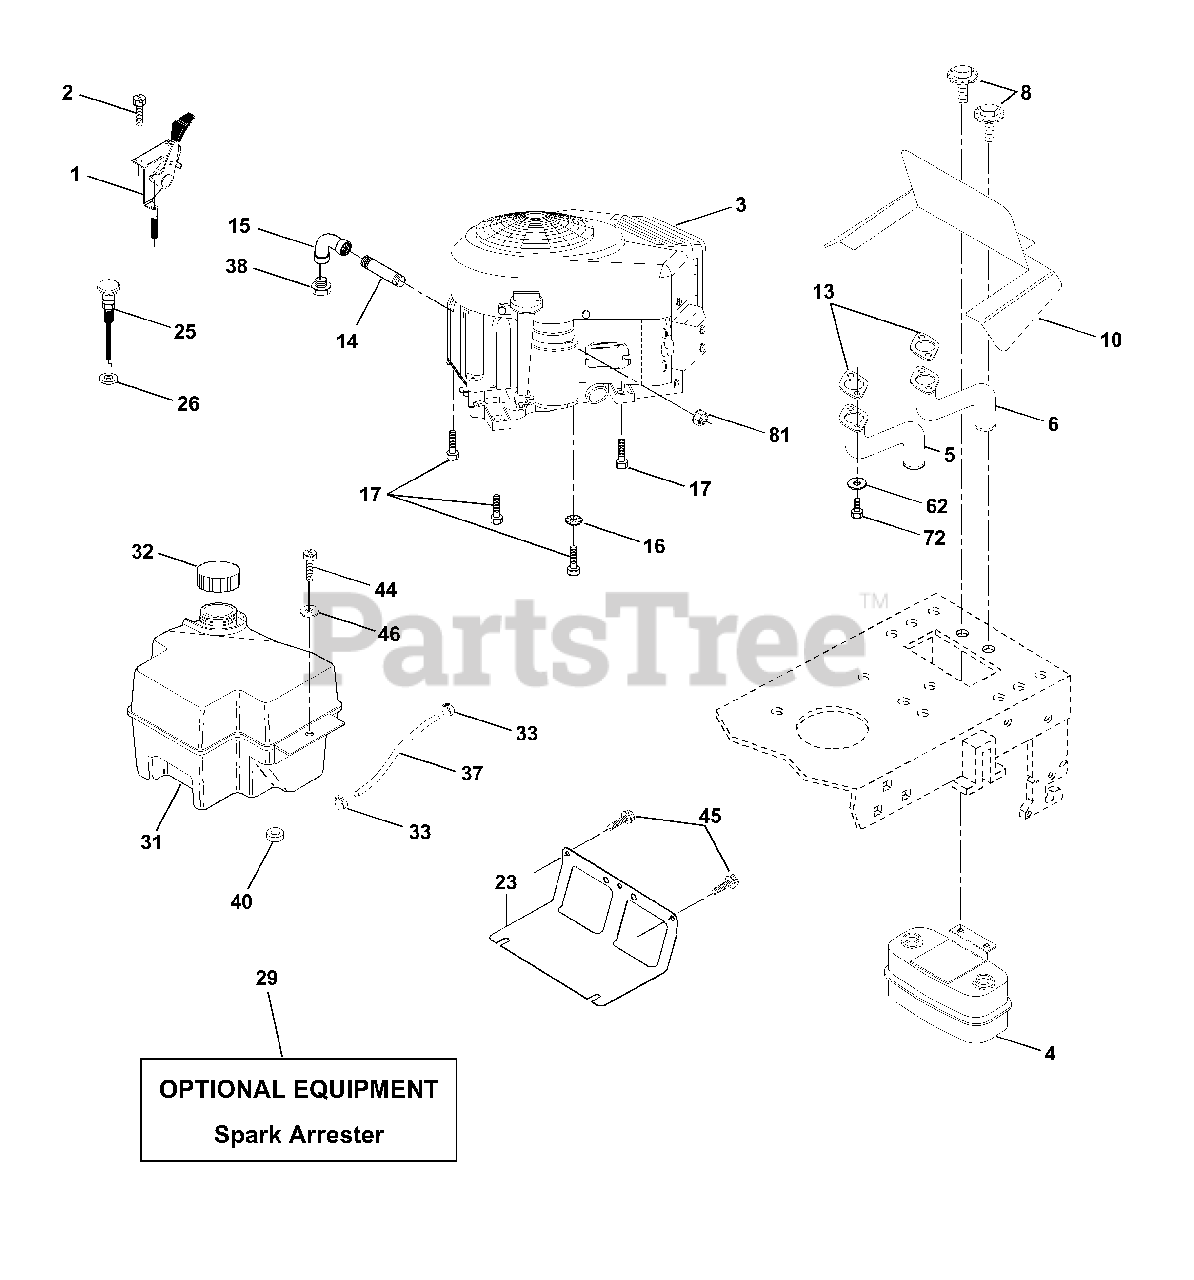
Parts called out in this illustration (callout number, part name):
1	Control, Throttle
4	Muffler, Asm. Twin Lo-Tone
5	Pipe Exhaust Intek 20 RH
6	Pipe Exhaust Intek 20 LH
8	Bolt 5/16-18 UNC x 3/4
10	Shield Browing B&S Intek II
13	Muffler Gasket
14	Nipple, Pipe
15	Elbow, Standard 90°, 3/8-18 NPT
16	Washer, Lock Ext tooth 3/8
17	Screw Thdrol 3/8-16 x 1-1/2
23	Shield, Browning/Debris Guard
25	Control Choke
26	Nut Keps 3/8-24 UNF
29	Arrester, Spark
31	Tank, Fuel
32	Cap Gauge, Fuel
33	Clamp, Hose Blk
37	Line, Fuel
38	Plug, Oil Drain
45	Screw Hex Wsh Thdrol 3/8-16 x 3/4
62	Washer Lock Hvy Hlcl Spr 5/16
72	Screw Hex Hd Cap 5/16-18 x 3/4
81	Nut Keps Hex 1/4-20 Unc
